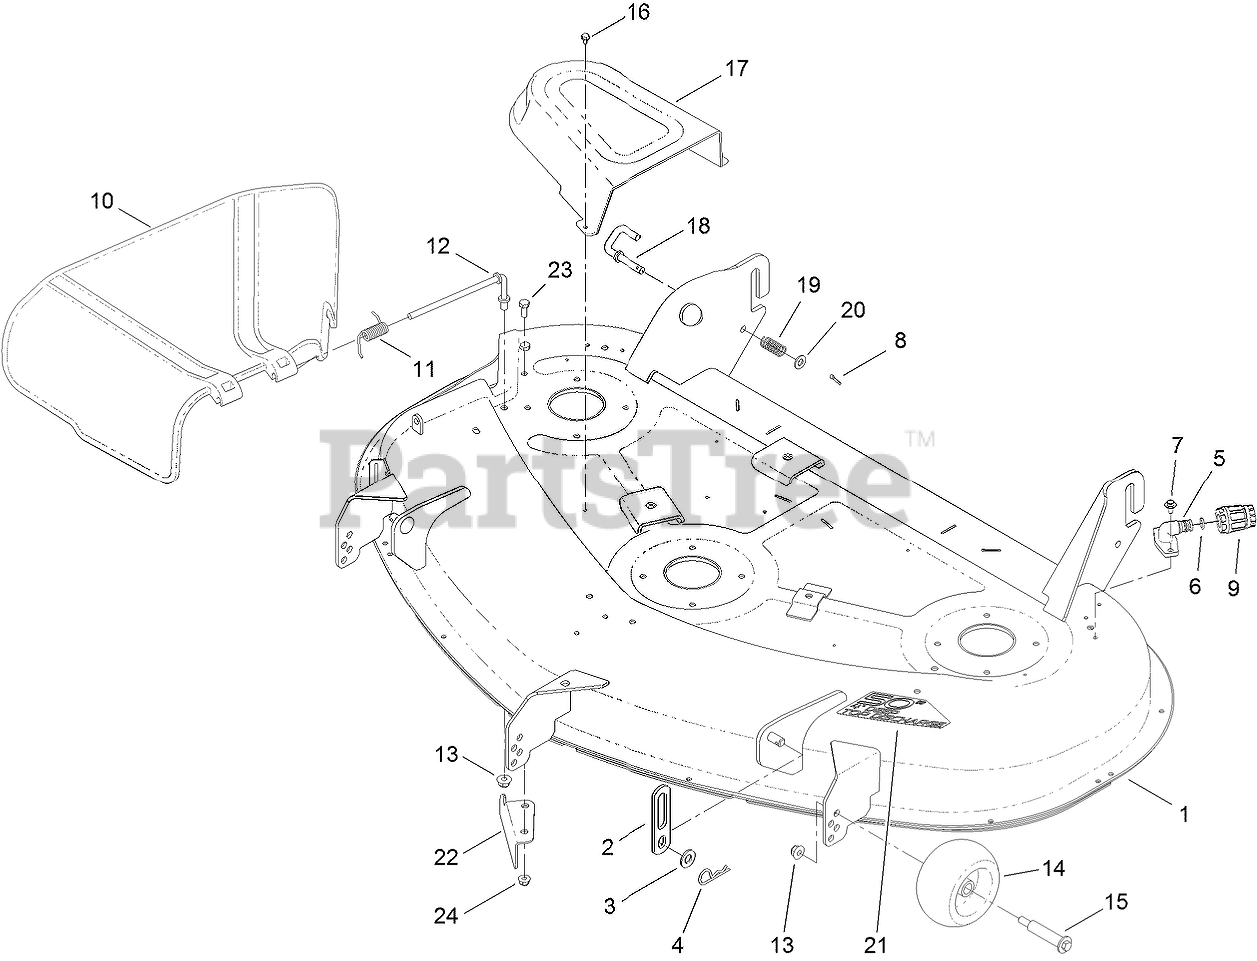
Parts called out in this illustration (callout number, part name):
1	50 INCH DECK ASM
2	LINK-LIFT
3	WASHER-FLAT
4	PIN-COTTER
5	FITTING-WASHOUT
6	O-RING
7	SCREW-HHFTF
8	PIN-COTTER
9	CONNECTOR-HOSE
10	DEFLECTOR
11	SPRING-TORSION
12	ROD-PIVOT
13	NUT-HF, NI
14	ROLLER-SCALP, ANTI
15	BOLT-SHOULDER
16	SCREW-HWHTF
17	COVER-BELT
18	PIN-LATCH
19	SPRING-COMPRESSION
20	WASHER-FLAT
21	DECAL-50 INCH
22	BAFFLE-CUTOFF
23	SCREW-HH
24	NUT-HF, NI
